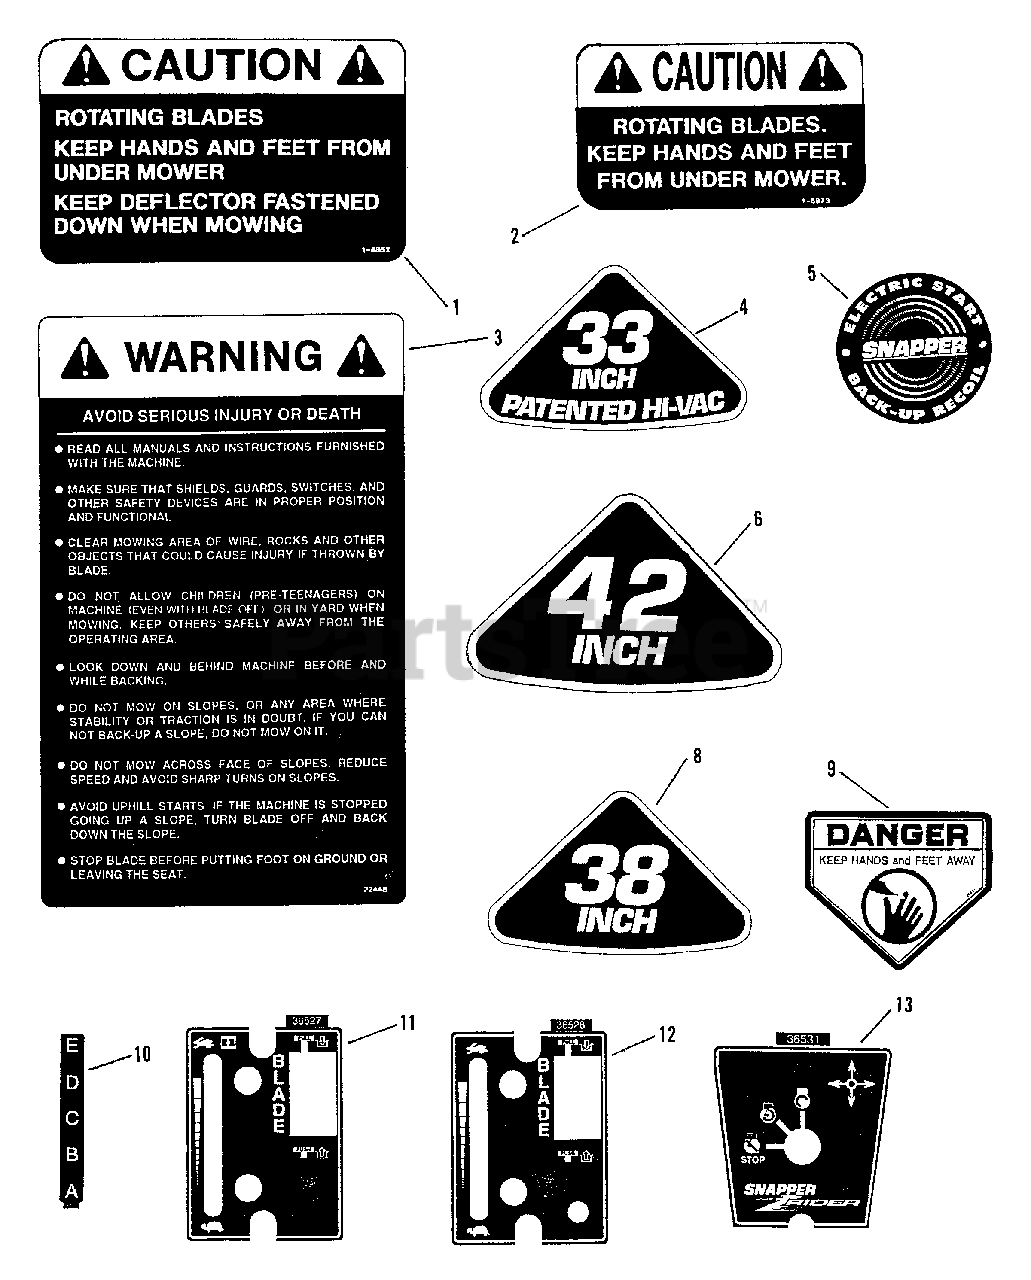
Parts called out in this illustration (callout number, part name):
1	DECAL, Caution
2	DECAL, Caution
3	DECAL, Safety Instructions
4	DECAL, 33"
5	DECAL, Back-Up Recoil
6	DECAL, 42"
8	DECAL, 38"
9	DECAL,CPSC
10	DECAL, Deck Height
11	DECAL, Throttle Control
12	DECAL, Throttle Control
13	DECAL, Ignition Switch
